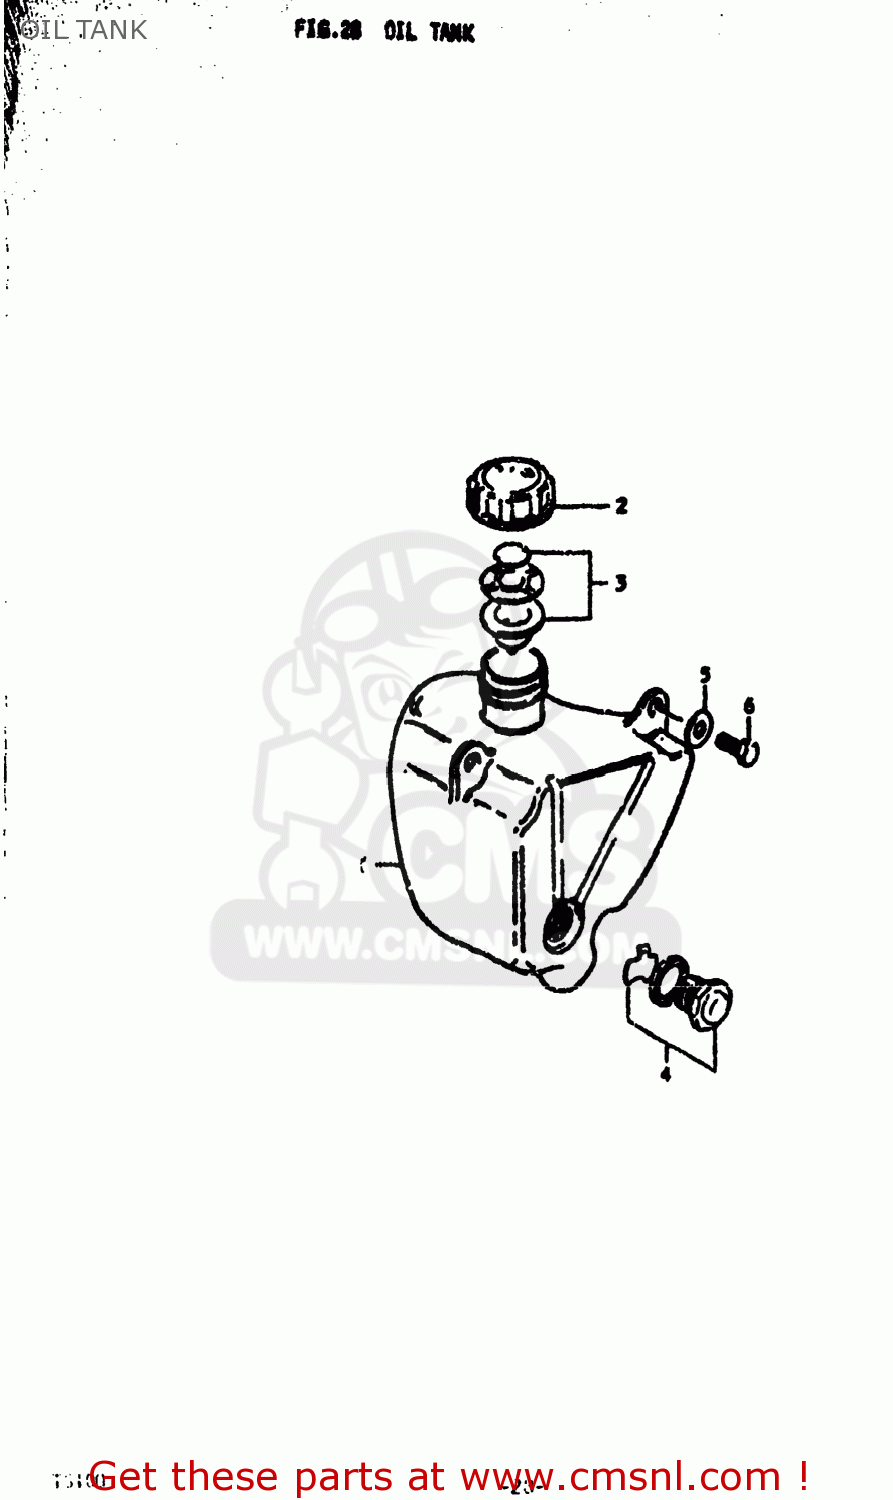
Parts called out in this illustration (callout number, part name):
1	TANK,OIL
2	CAP,OIL TANK
3	GASKET SET (NAS)
4	LENS SET,OIL LEVEL
5	WASHER
